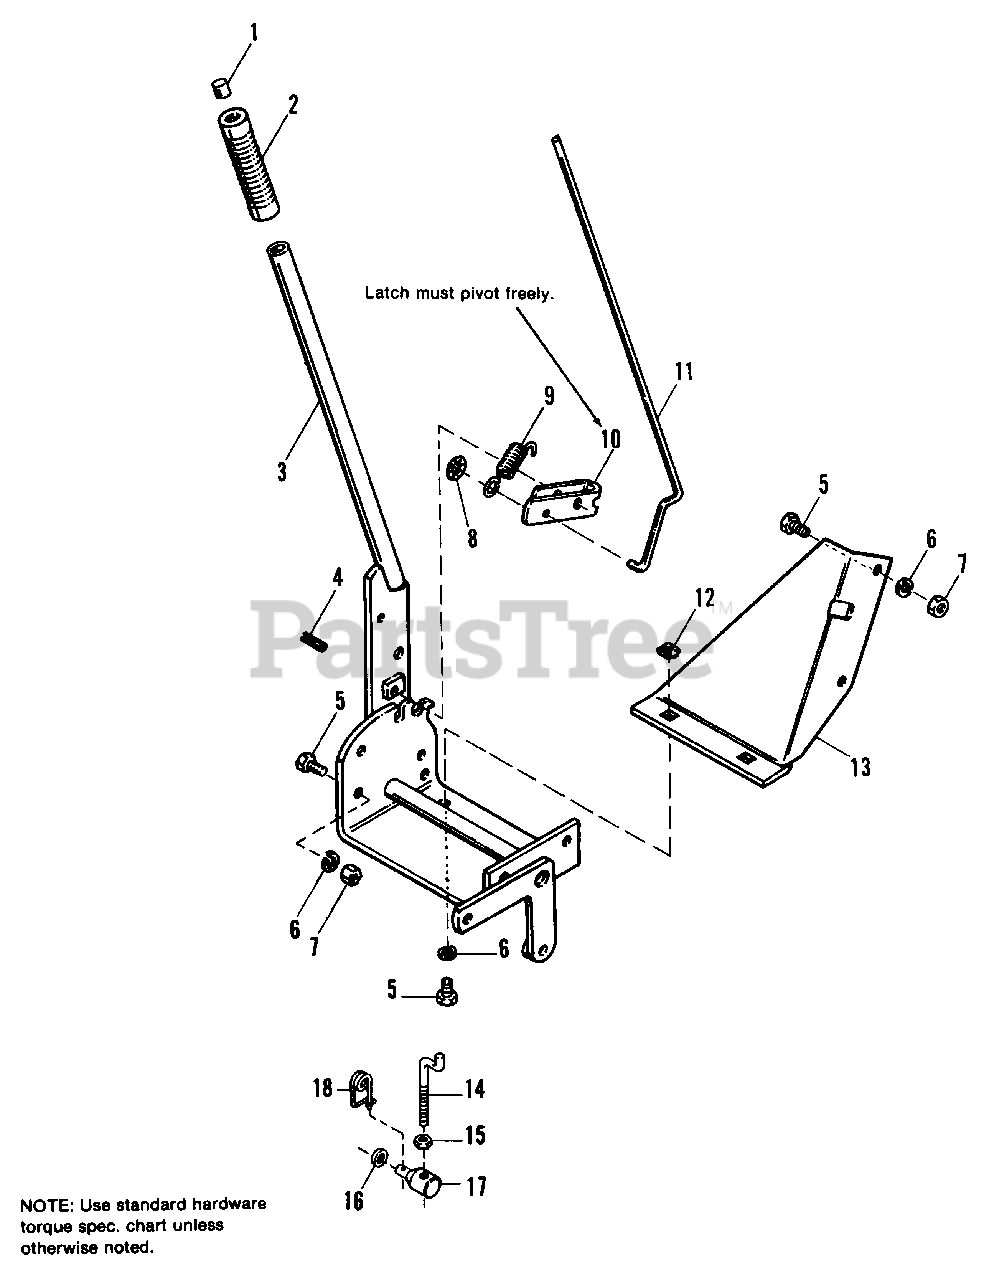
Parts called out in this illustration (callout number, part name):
2	GRIP
3	LEVER ASSY., Lift
4	PIN, Roll
5	CAPSCREW, Hex Hd., 5/16-18 x 3/4
6	LOCKWASHER, 5/16
7	NUT, Hex, 5/16-18
10	LATCH, Lever
12	NUT, Speed, 5/16-18
13	BRACE, Lift Lever
15	NUT, Jam, 5/16-18
16	WASHER, 5/16
17	TRUNNION, Pivot
18	CLIP, Safety
